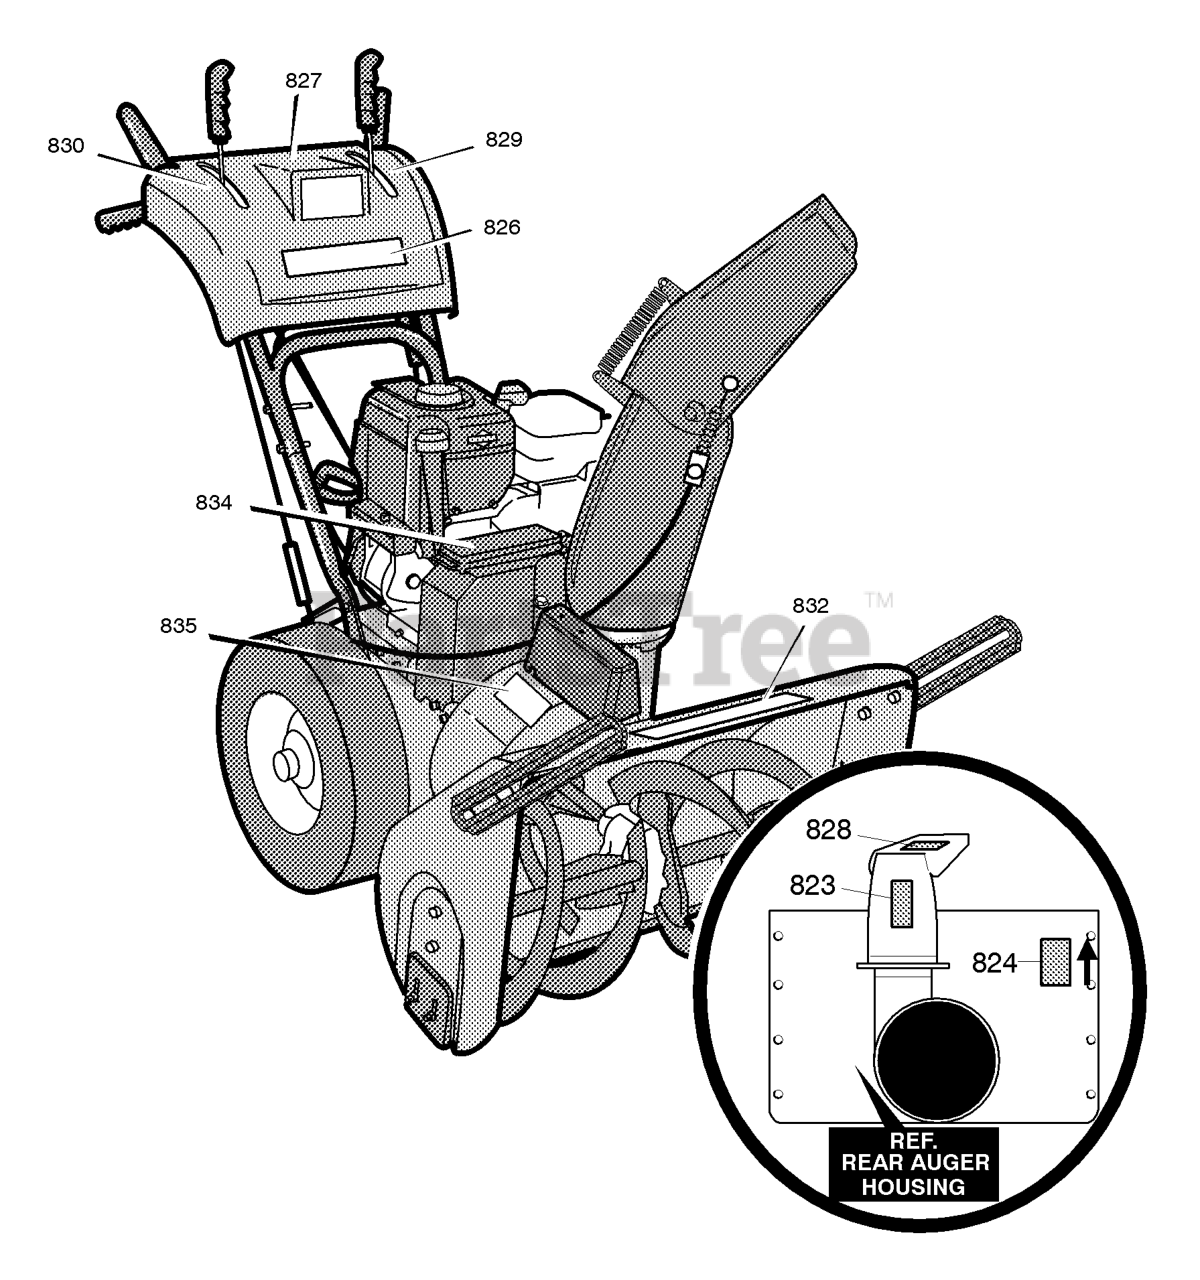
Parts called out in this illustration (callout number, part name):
823	DECAL, DANGER CHUTE HAND
824	DECAL, DANGER FOOT
826	DECAL, CRAFTSMAN
827	DECAL, SINGLE HAND CONTROL
828	DECAL, THROWN OBJECTS
829	DECAL, REMOTE CHUTE ELECTRIC
830	DECAL, TRANS
832	DECAL, CRAFTSMAN 13/33
834	DECAL, TOOLBOX INFORMATION
835	DECAL, PINCH POINT ELECTRIC
